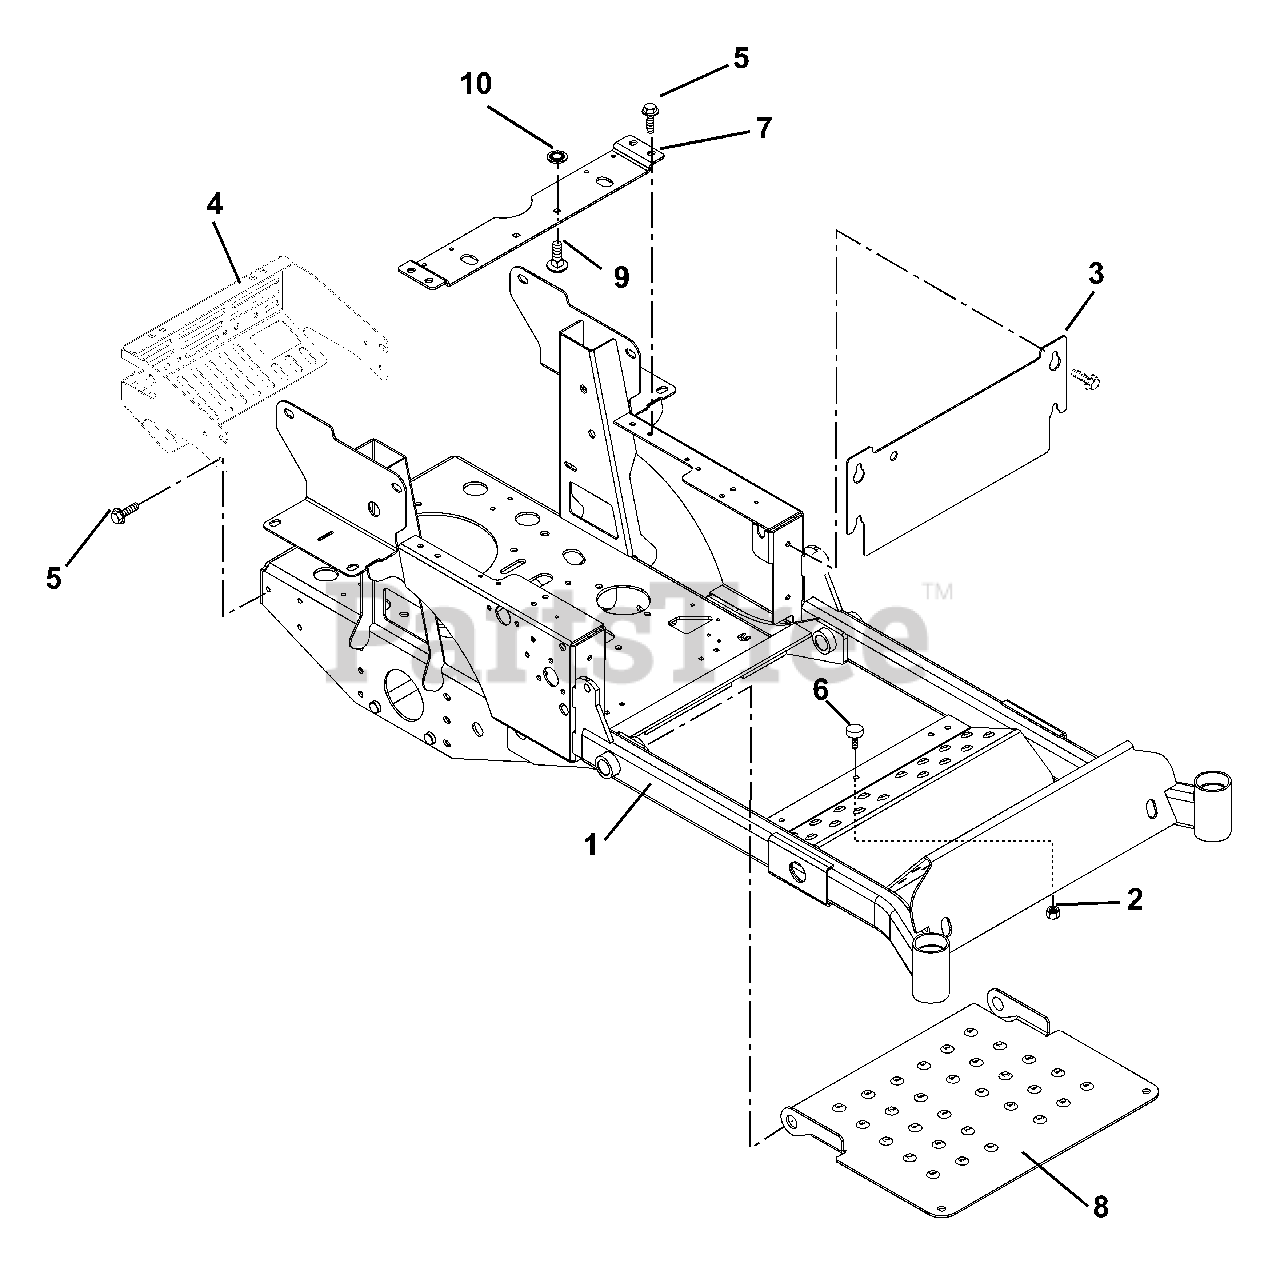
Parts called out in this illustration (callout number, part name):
1	Frame, Compact-Z
2	Nut, Spin Lock Flange .312-18
3	Access Panel
4	Bumper, Rear
5	Screw, Tapping .38-16 x .75 Hex Washer Head
6	Bumper, Rubber
7	Seat Support
8	Panel, Inspection
9	Bolt, Round Head Square Short Neck .31-18 x .74 Grade 5
10	Nut, Push .312
